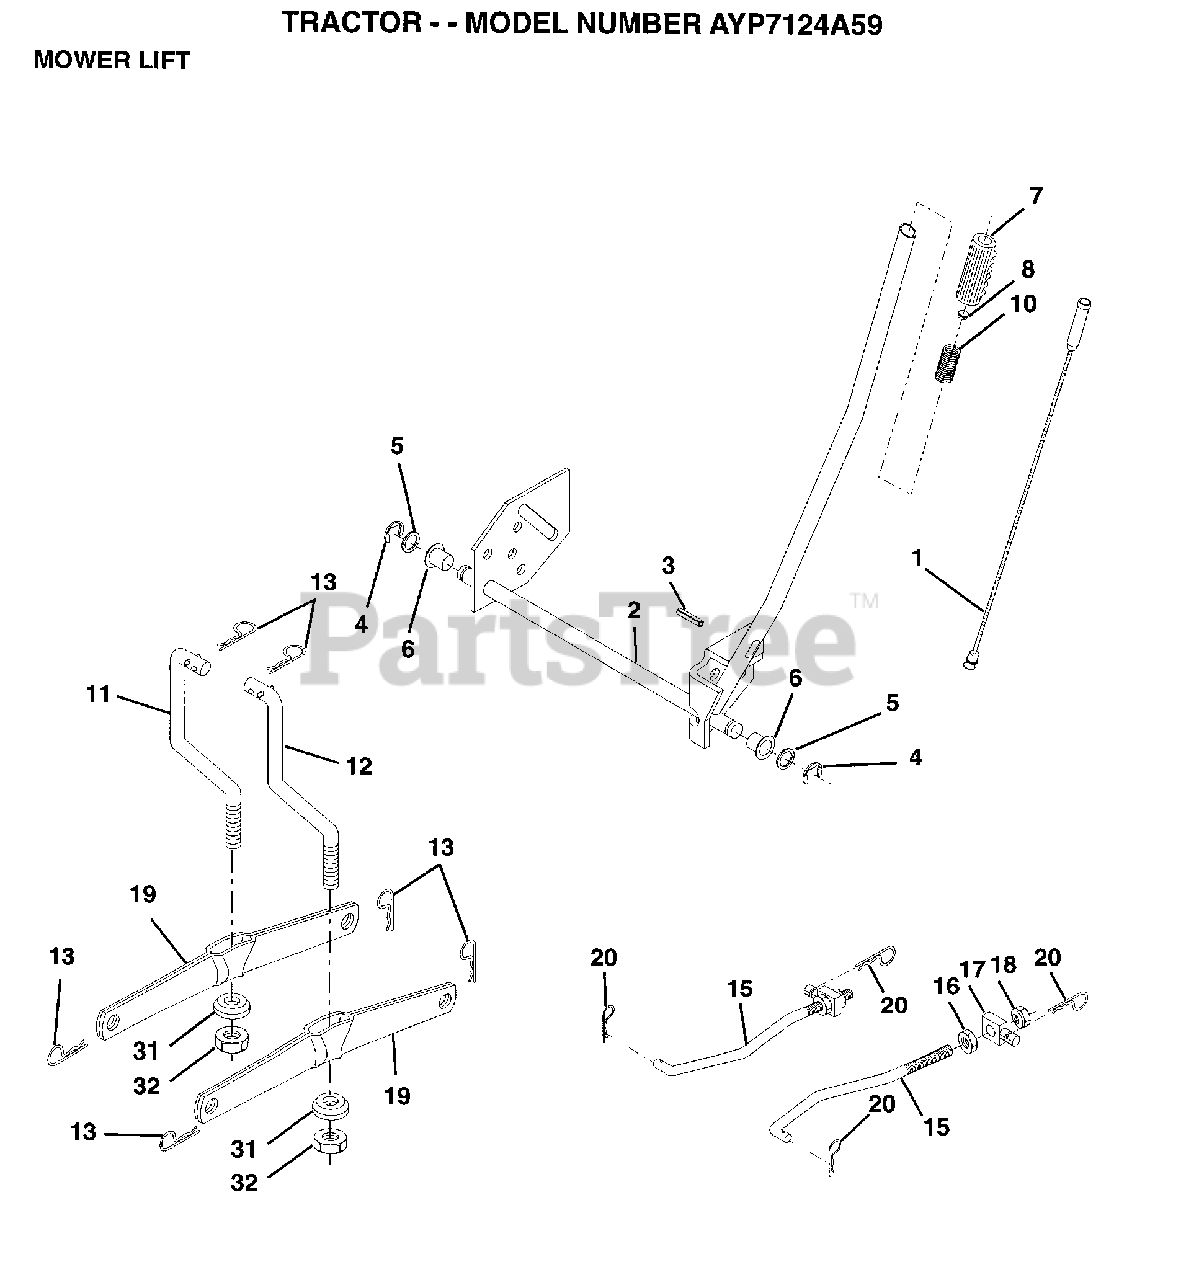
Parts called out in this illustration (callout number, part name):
1	WIRE ASM
3	PIN-GROOVE LT
5	WASHER
6	NYLON BEARING
7	GRIP
15	LINK.FRONT
16	NUT
17	TRUNION
18	NUT.LK.W/WSH.1/2.
19	ARM SUSP REAR
20	RETAINER.SPRING
31	BEARING PVT LH
32	NUT.CROWNLOCK.3/8
